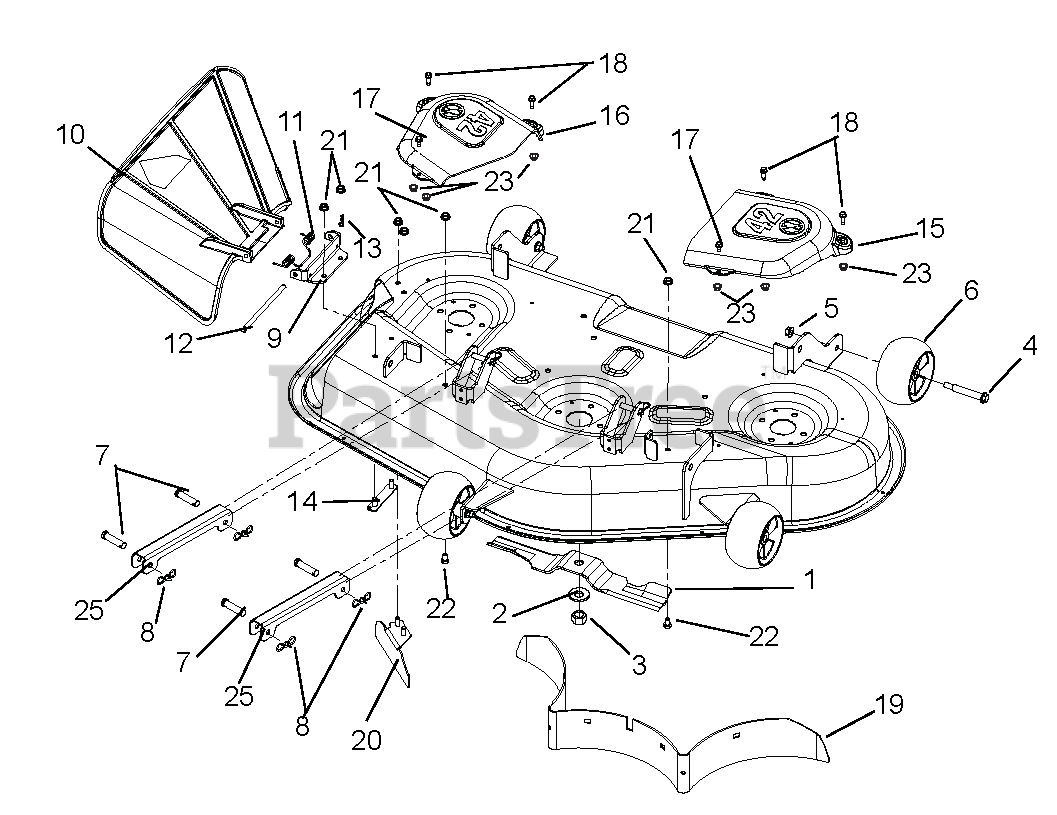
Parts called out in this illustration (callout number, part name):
1	BLADE, MOWER 14.83 (.188 THK)
2	WSHR-BLVL .669X1.535X.138
3	NUT-HEX .62-18 YWZC
4	BLT-SHLDR .38-16X2.50 HWH G5
5	@NUT-LK-TOP-FLG .38-16 YWZC
6	ANTI-SCALP WHEEL - 5X OS
7	PIN-CLEV .375 X 2.00 YWZC
8	PIN, BOW TIE LOCKING
9	BRKT-DISCHARGE CHUTE MOUNT 42"
10	DISCHARGE CHUTE
11	SPRING-TORSION
12	PIN, 5/16 X 5.80"
13	PIN-HAIR INT .08X.18X1.18 YWZC
14	WMT-DISCHARGE CHUTE MT. STRAP
15	BELT COVER - LH 42"
16	BELT COVER - RH 42"
17	SCR-TAP .25-20X.50 HWH TR YWZ
18	SCR-TAP .25-20X.75 HWH TR YWZ
19	BAFFLE, REAR (42)
20	WMT, DISCHARGE BAFFLE (42)
21	@NUT-LK-TOP-FLG .31-18 YWZC
22	@BLT-HEX .31-18X.50 GR5 YWZC
23	NUT-PUSH .25X.50 O.D.
24	ROLLER
25	BRKT-STABILIZER LINK
